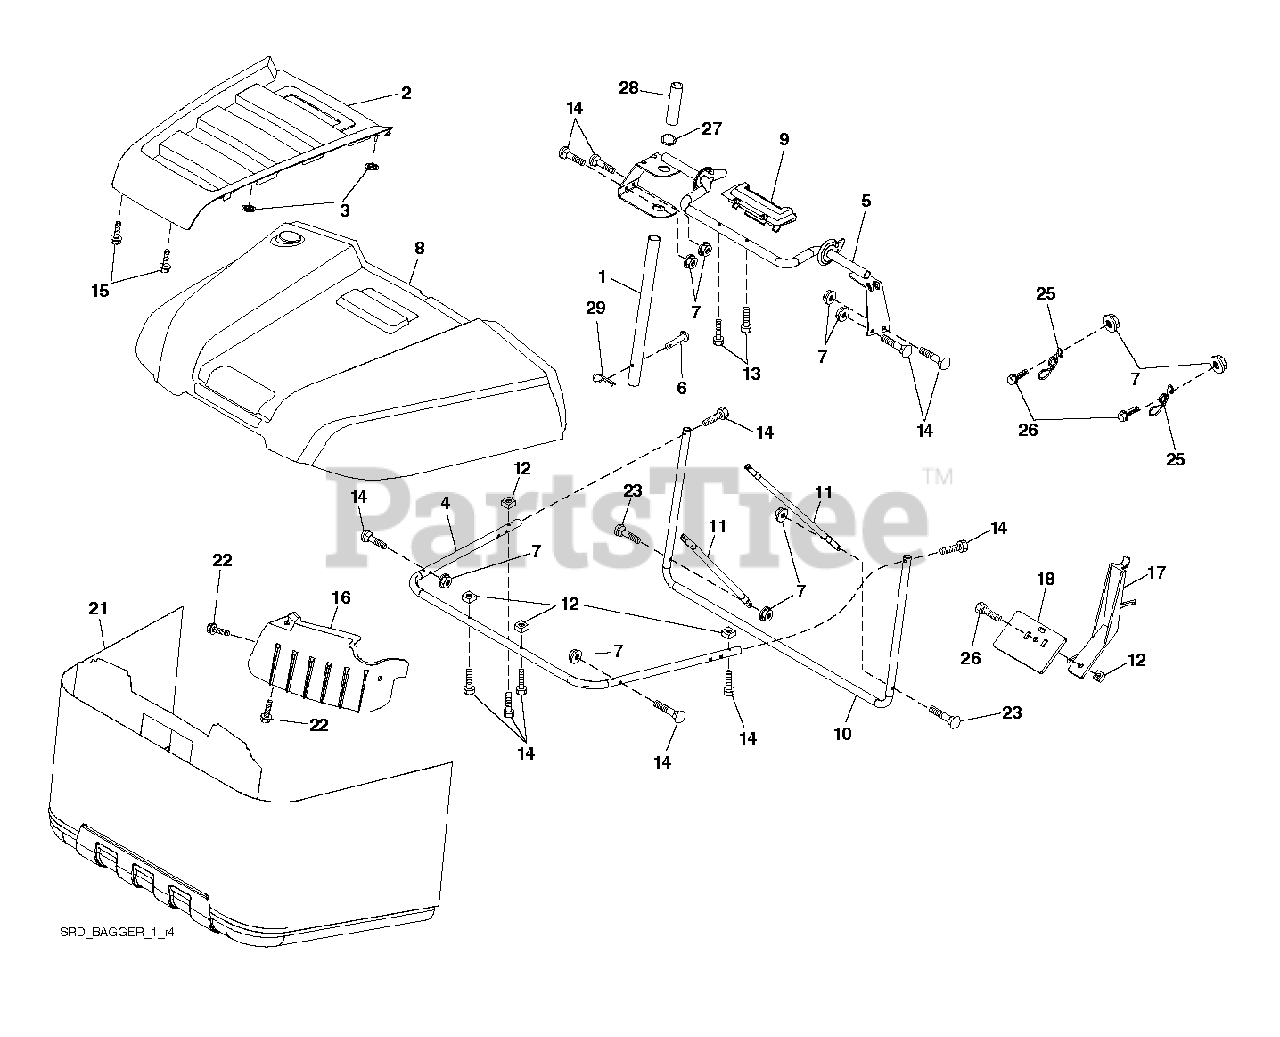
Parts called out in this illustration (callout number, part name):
1	TUBE.HANDLE.BAGGER.CRD/SRD.BLA
2	APPLIQUE.TOP.BAG.SRD.ORANGE
3	NUT.PUSH.156
4	SUBASM.TOP.TUBE.TEX.CRD
5	FRAME.ASM.TOP.BAGGER.SRD
6	RIVET,DRILLED
7	NUT T
8	BAGGER.TOP.SRD.APPLIQUE
9	INSERT.HANDLE.BAGGER.(2 2)
10	FRAME.FRONT.SRD.BAGGER
11	TUBING.BRACE.BAGGER.SRD.BLACK
12	NUT.SQUARE.1/4
13	SCREW.1/4X1.150.HXWSH
14	BOLT.SHOULDER.HX.WSH.1/4X1.150
15	SCREW,#8.FLAT.HEAD.DRILL.TIP
16	DEFLECTOR.BAGGER.SRD
17	LEVER.BAGGER.FULL.SRD.BLACK
18	PADDLE.BAGGER.FULL.SRD.BLACK
21	BAG.ASM.BAGGER.SRD.HUSQVA.GREY
22	SCREW.HI-LO.CONSOLE
25	SPRING.LATCH.BAGGER.SRD
26	SCREW HEX CRT
27	RB GROMMET.RUBBER.SRD
28	GRIP.HANDLE.BLACK
29	PIN.COTTER.5/16.BOW TI
